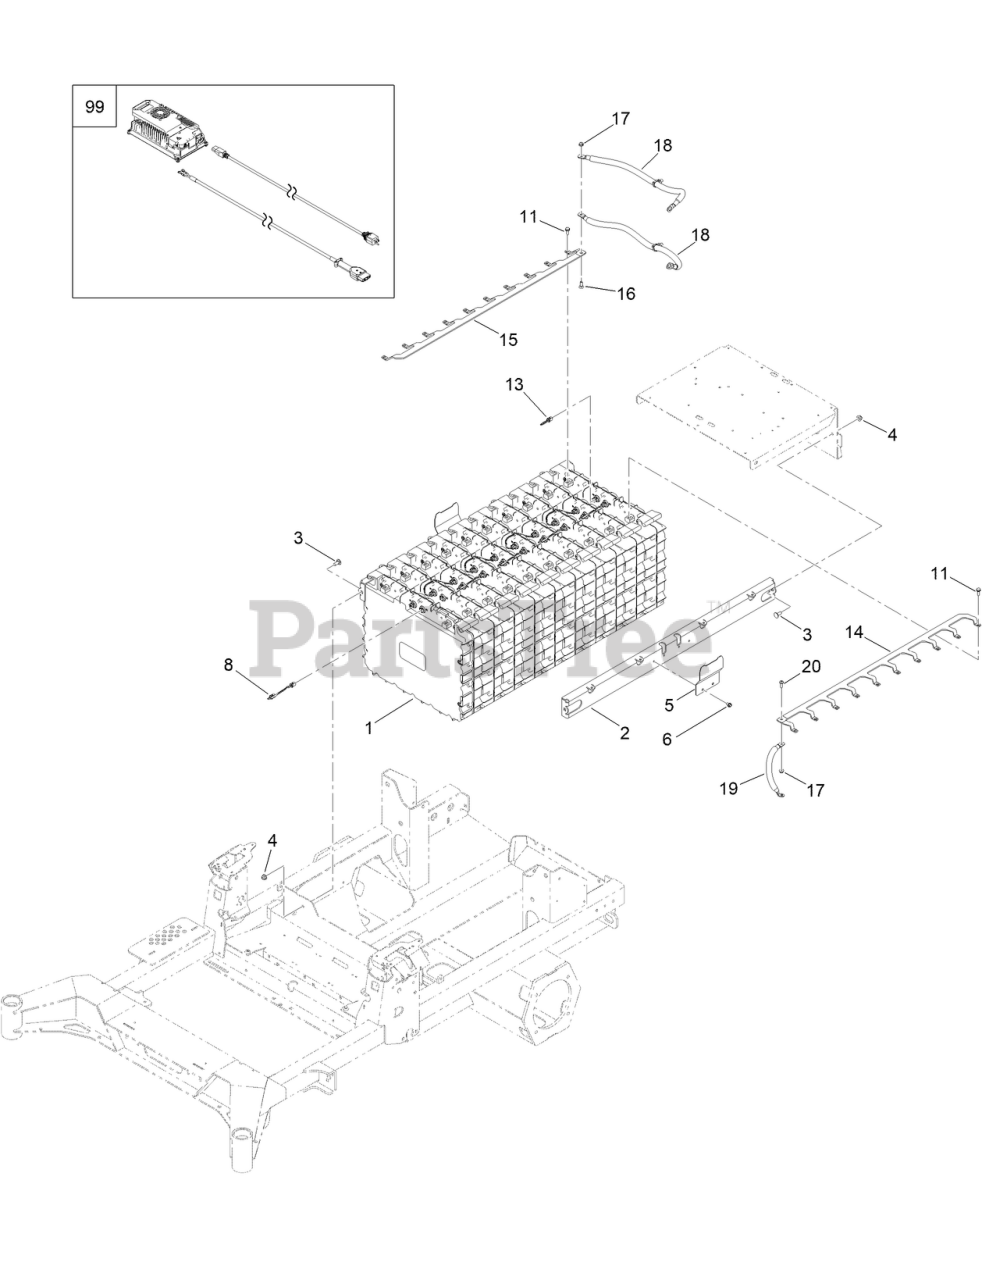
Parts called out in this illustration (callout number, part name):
1	BATTERY ASM
2	PLATE-RETAINER
3	SCREW-CARR
4	NUT-HF, NI
5	PLATE-COVER
6	SCREW-HWH
8	HARNESS-WIRE, DATA INTERFACE
11	SCREW-SEMS
13	HARNESS-WIRE, CAN TERMINATOR
14	BUSBAR-10, BK
15	BUSBAR-10, RD
16	BOLT-CARR
17	NUT-HF
18	CABLE-BATTERY, RD ASM
19	CABLE-BATTERY, BK ASM
20	SCREW-PH
99	CHARGER-1200W
